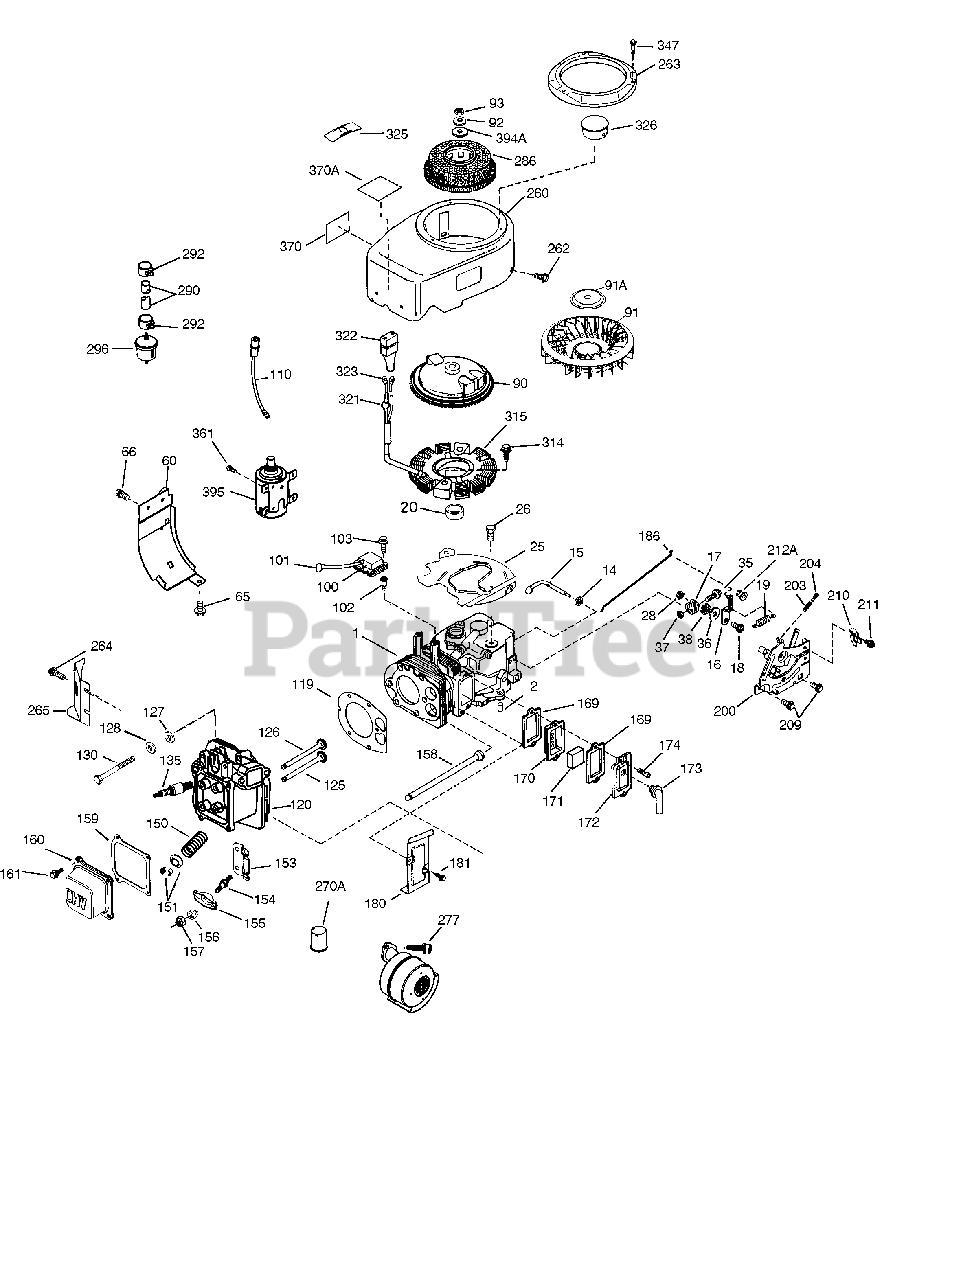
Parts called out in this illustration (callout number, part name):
1	"Cylinder (Incl. 2 & 20)
2	Dowel Pin
14	Flat Washer
15	Governor Rod
16	Governor Lever (Incl. 212A)
17	Governor Lever Clamp
18	Screw, Torx T-15, 8-32 x 3/8"
19	Extension Spring
20	Oil Seal
25	Blower Housing Baffle
26	Screw, 1/4-20 x 5/8"
28	Lock Nut, 8-32
35	Screw, 10-32 x 3/4"
36	Lock Washer #8
37	Lock Nut, 10-32
38	Retaining Ring
47	Connecting Rod Bolt
60	Blower Housing Extension
62	Screw, 8-32 x 3/8"
63	Breather Tube Grommet
65	Screw, 10-24 x 1/2"
66	Screw, T-30, 1/4-20 x 1/2"
68	Ground Terminal
90	Flywheel (W/Ring Gear)
92	Lock Washer
93	Flywheel Nut
100	Solid State Ignition
101	Spark Plug Cover
102	Solid State Mounting Stud
103	Screw, Torx T-15, 10-24 x 1"
110	Ground Wire
119	* Cylinder Head Gasket
120	Cylinder Head
123	Intake Pipe Brace
124	Screw, 1/4-20 x 9/16"
125	Exhaust Valve (Std.)
125	Exhaust Valve (1/32" OS)
126	Intake Valve (Std.)
126	Intake Valve (1/32" OS)
128	Belleville Washer
130	Screw, 5/16-18 x 2-45/64"
135	Resistor Spark Plug (RN4C) also avail able in Packaged Part #740069
150	Valve Spring
151	Valve Spring Keeper
153	Push Rod Guide
154	Rocker Arm Stud
155	Rocker Arm
157	Lock Nut, 5/16-24
158	Push Rod
159	* Rocker Arm Cover Gasket
160	Rocker Arm Housing
161	Screw, T-30, 1/4-20 x 1/2"
169	* Breather Gasket
170	Breather Body
171	Breather Element
172	Valve Cover
173	Breather Tube
174	Screw, 10-24 x 1/2"
180	Blower Housing Extension
181	Screw, 10-24 x 9/16"
186	Governor Link
186A	Choke Link
200	Control Bracket (Incl. 203 & 204)
203	Compression Spring
204	Screw, 6-32 x 21/32"
209	Screw, 10-32 x 7/16"
210	Conduit Clip
211	Screw, 10-32 x 3/8"
212A	Bushing
237	Air Filter Adapter
238	Screw, 10-32 x 5-1/4"
260	Blower Housing
261	Screw, T-30, 1/4-20 x 1/2"
262	Screw, T-40, 5/16-24 x 21/32"
263	Trim Ring
264	Screw, 5/16-18 x 5/8"
264A	Screw, T-30, 1/4-20 x 1/2"
265	Cylinder Head Cover
266	Screw, 5/16-18 x 1-1/4"
269	* Exhaust Manifold Gasket
270	Exhaust Manifold
270A	Exhaust Port Liner
271	Locking Plate (Manifold)
275	Muffler
276	Locking Plate
277	Screw, 5/16-18 x 4-1/2"
290	Fuel Line
292	Fuel Line Clamp
296	Fuel Filter (Incl. 292) also availabl e as Packaged Part #740003B
308	Fill Tube Clip
308A	Fill Tube Clip
314	Screw, 1/4-20 x 3/4"
315	Alternator Coil (3 Amp) Incl. 321 - 3 23
322	Connector Body
323	Terminal
325A	Wire Clip
326	Blower Housing Plug
337	Deflector
347	Screw, 10-32 x 9/16"
361	Screw, Torx T-30, 5/16-18 x 15/32"
370G	Decal - Important Lubrication - SAE 3
370R	Warning Decal
393	Cup & Screen
395	Electric Starter Motor (12 Volt)
414	Spark Arrestor Screen (Incl. 417)
900	Replacement Engine None
900	Replacement Short Block 752321, order from 71-999
